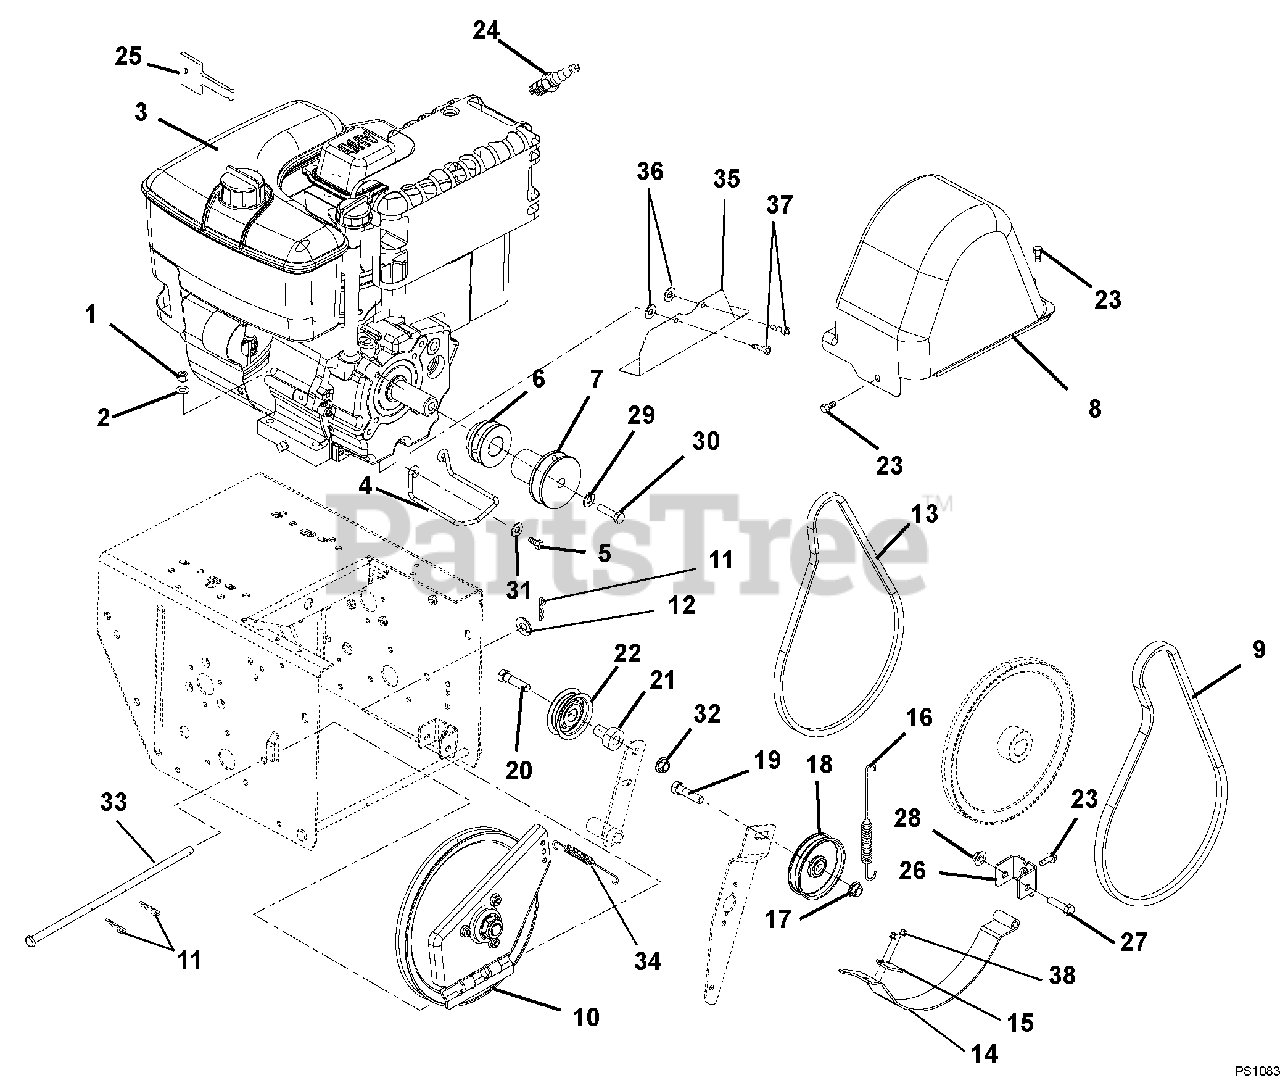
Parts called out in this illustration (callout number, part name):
1	Nut, Hex .31-18
2	Washer, Lock .312 x .097
3	Engine, 9HP Tecumseh OH318EA - 222719E
4	Belt Finger
5	Bolt, Hex .31-24 x .75 Grade 5
6	Sheave, Drive
7	Sheave, Attachment
8	Cover, Belt
9	V-Belt 4L
10	Plate, Deep Swing Assembly
11	Hair Pin
12	Washer, Flat Steel .406 x .812 x .065
13	V-Belt,Traction Drive 3L
14	Arm, Brake Attachment
15	Pad, Brake (included with item 14)
16	Spring, Tension
17	Nut, Locking Top Flange .38-16
18	Idler, Flat 3.00
19	Bolt, Hex .38-16 x 1.50 Grade 5
20	Bolt, Hex .31-18 x 1.25 Grade 5
21	Spacer, Bearing
22	Idler
23	Screw, Tapping .25-20 x .50 Hex Washer Head Thread Rolling
24	Plug, Spark
25	Key, Push/Pull Tecumseh
26	Pivot, Brake
27	Bolt, Hex .31-18 x 2.00 Grade 5
28	Nut, Locking-Top-Flange .31-18
29	Washer, Locking .38 x .094
30	Bolt, Hex .38-24 x 2.0
31	Washer, Locking .312 x .097 Heavy
32	Nut, Locking-Top-Flange .31-18
33	Rod, Pivot
34	Spring, Tension
35	Baffle, Engine
36	Washer, Flat Steel .536 x 1.07 x .109
37	Screw, Machine .31-24 x .75 EP80
38	Rivet, Pop .187
